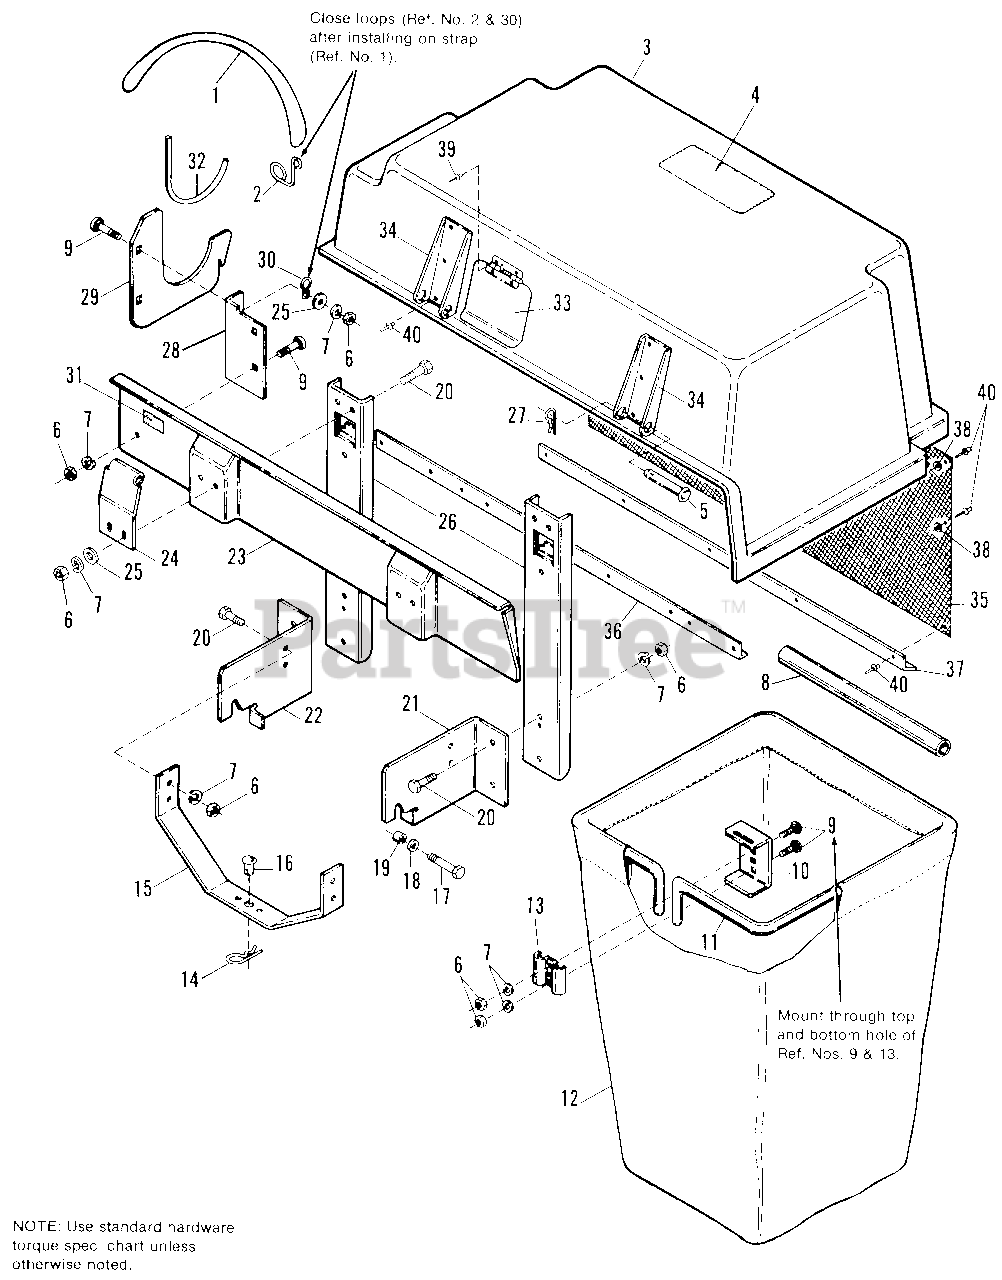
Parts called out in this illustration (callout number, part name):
2	HOOK, Strap
3	COVER ASSY. (Incl. Ref. Nos. 4, 33 & 34)
4	DECAL, Warning
6	NUT, Hex, 5/16-18
7	LOCKWASHER, 5/16
9	BOLT, Carriage, 5/16-18 x 7/8 (Qty. 9 Deluxe only)
14	CLIP, Hairpin
15	BRACE, Lower
17	CAPSCREW, Hex, 3/8-16 x 1-1/4
18	WASHER, 3/8
20	CAPSCREW, Hex, 5/16-18 x 7/8
21	SUPPORT, L.H.
22	SUPPORT, R.H.
23	PLATE, Support, Cover
24	PLATE, Hinge
25	WASHER, 3/8 x 7/8
26	BRACE, Upper
27	CLIP, Hairpin
28	MOUNT, Saddle Bracket
29	BRACKET, Saddle Assy.
33	DOOR & HINGE
34	HINGE, Bracket
36	BRACKET, Front Cover
37	BRACKET, Rear Cover
38	WASHER, Rivet
